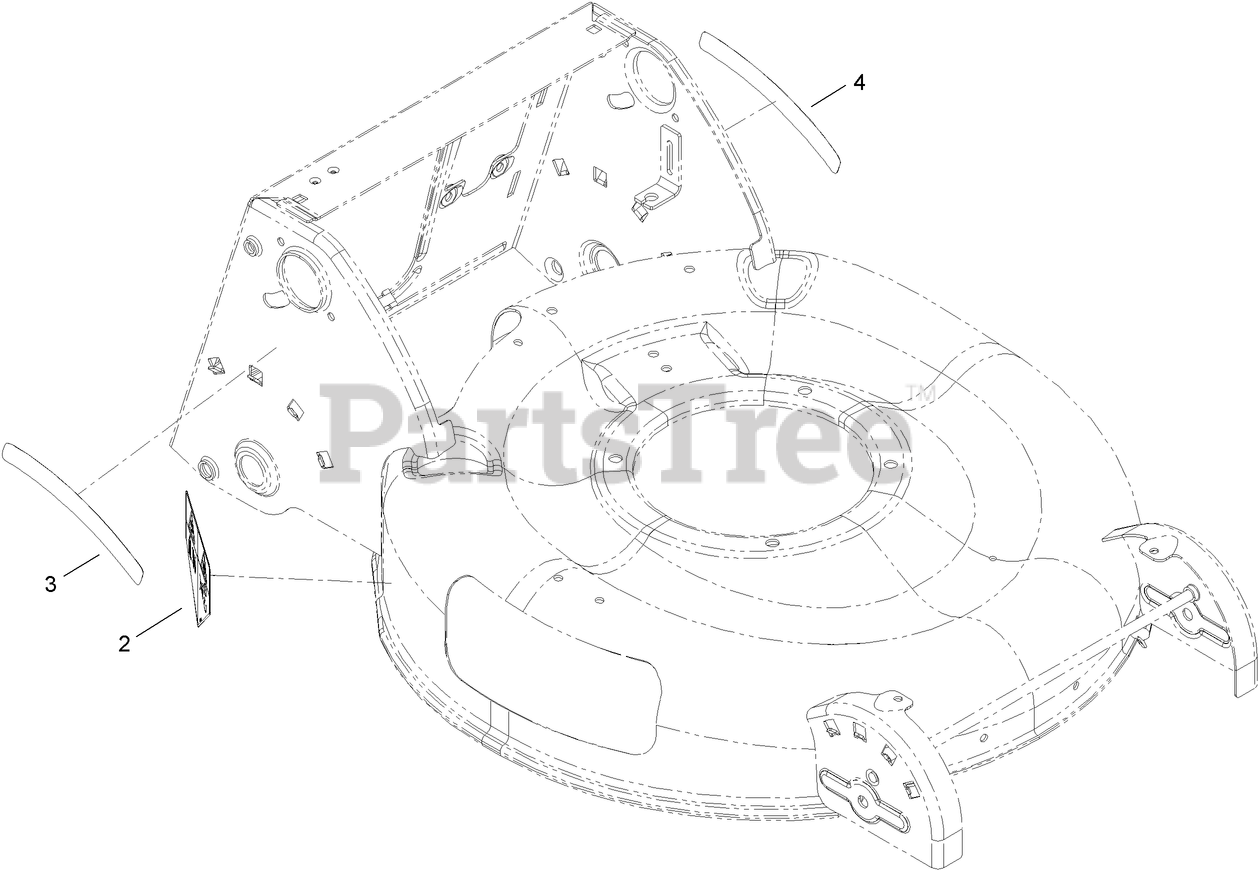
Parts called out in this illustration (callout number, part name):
2	DECAL-DANGER
3	DECAL-HOC, RH
4	DECAL-HOC, LH
